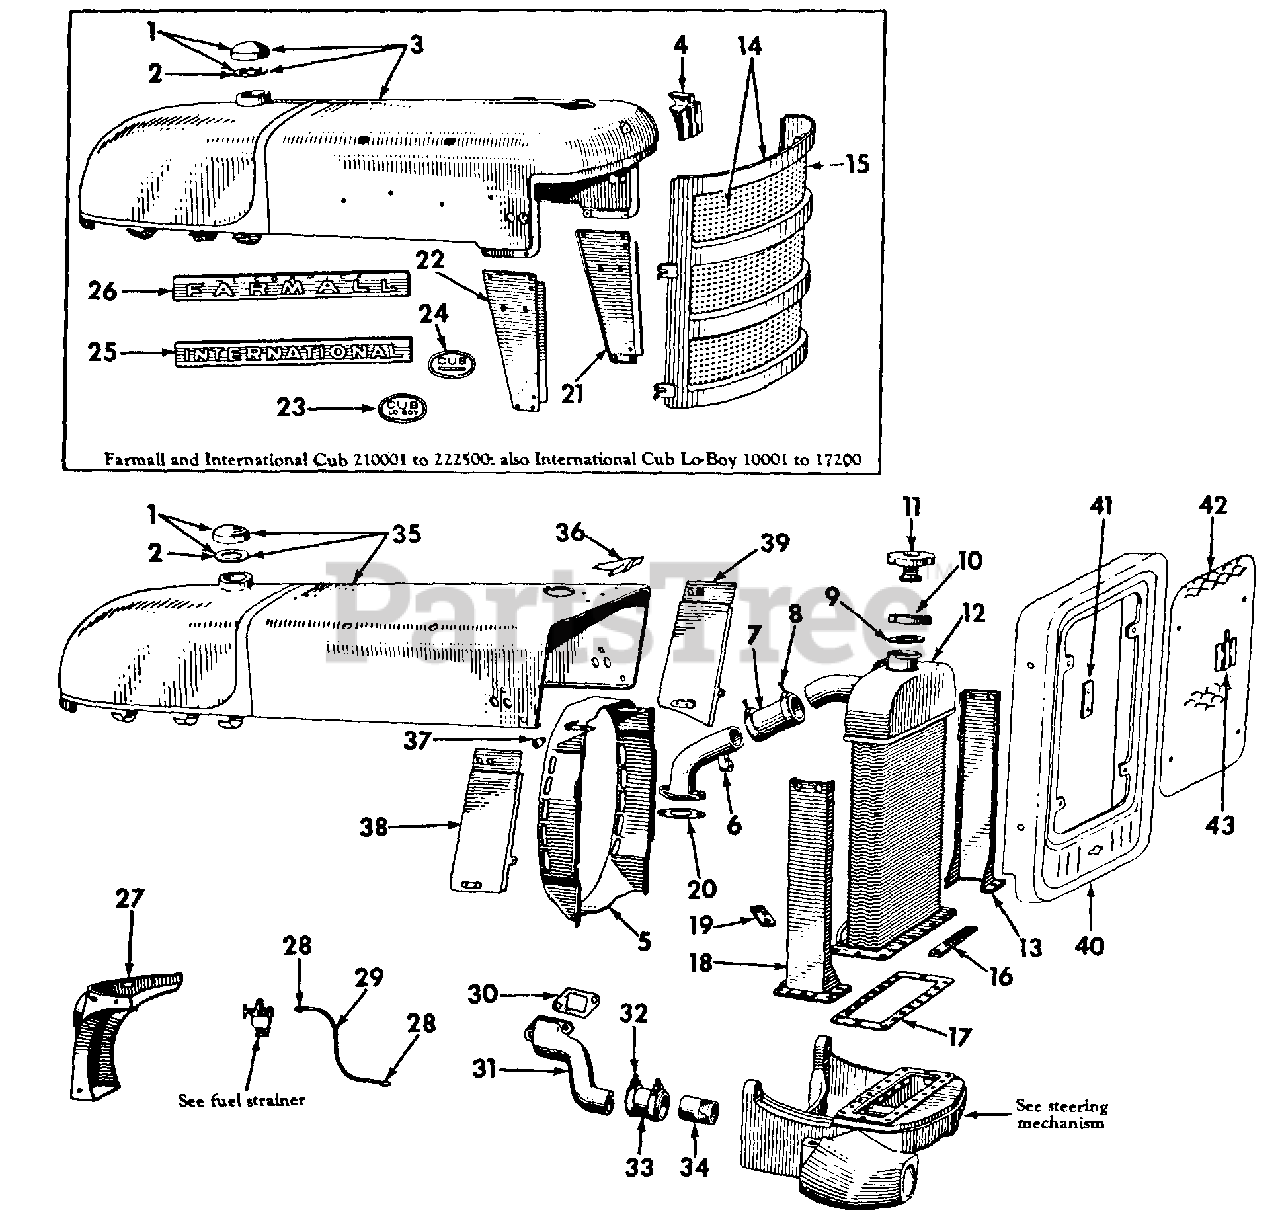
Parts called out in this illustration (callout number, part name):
1	CAP ASSY FUEL TANK FILLER
2	GASKET, FUEL TANK FILLER CAP
3	HOOD AND FUEL TANK ASSY
4	EMBLEM, IH HOOD
5	HOUSING, FAN
6	ELBOW, WATER OUTLET
7	HOSE, 1-3/4 IN. ID X 4 IN LONG, 1 PLY RADIATOR INLET
8	CLAMP, RADIATOR HOSE
9	GASKET RADIATOR FILLER CAP
10	CAP, RADIATOR FILLER
10	CAP, RADIATOR
11	CAP, RADIATOR PRESSURE TYPE SPECIAL
11	CAP, RADIATOR PRESSURE TYPE
12	RADIATOR ASSY
13	CHANNEL, RADIATOR SIDE LH
14	GRILLE RADIATOR
15	SCREEN, RADIATOR GRILLE
16	PLATE, RADIATOR HOLD-DOWN
17	GASKET, RADIATOR
18	CHANNEL, RADIATOR SIDE RH
19	CLIP, RADIATOR OVERFLOW PIPE
20	GASKET, WATER OUTLET ELBOW
21	SIDE, RADIATOR GRILLE LH
22	SIDE, RADIATOR GRILLE RH
23	PLATE, CUB LO-BOY MODEL SYMBOL
24	PLATE, CUB MODEL SYMBOL
25	PLATE, INTERNATIONAL NAME
26	PLATE, MC CORMICK FARMALL NAME
27	PACKAGE, HOOD AND FUEL TANK SUPPORT SERVICE
27	SUPPORT, HOOD AND FUEL TANK
27	SUPPORT HOOD AND FUEL TANK
28	NUT, 1/2-20 HI-DUTY TUBE FITTING
29	PIPE, FUEL
30	GASKET, WATER INLET ELBOW
31	ELBOW, WATER INLET
32	CLAMP, RADIATOR HOSE
33	HOSE, 1-5/8 ID X 2 3/8 IN. LONG, 1 PLY RADIATOR OUTLET
34	NIPPLE, RADIATOR OUTLET
35	HOOD AND FUEL TANK ASSY
36	ORNAMENT, HOOD
38	SHEET, RADIATOR GRILLE RH
39	SHEET RADIATOR GRILLE LH
40	GRILLE ASSY, RADIATOR
41	PLATE, GRILLE EMBLEM MOUNTING
42	SCREEN, RADIATOR GRILLE
43	PRODUCT GRAPHIC, IH EMBLEM
